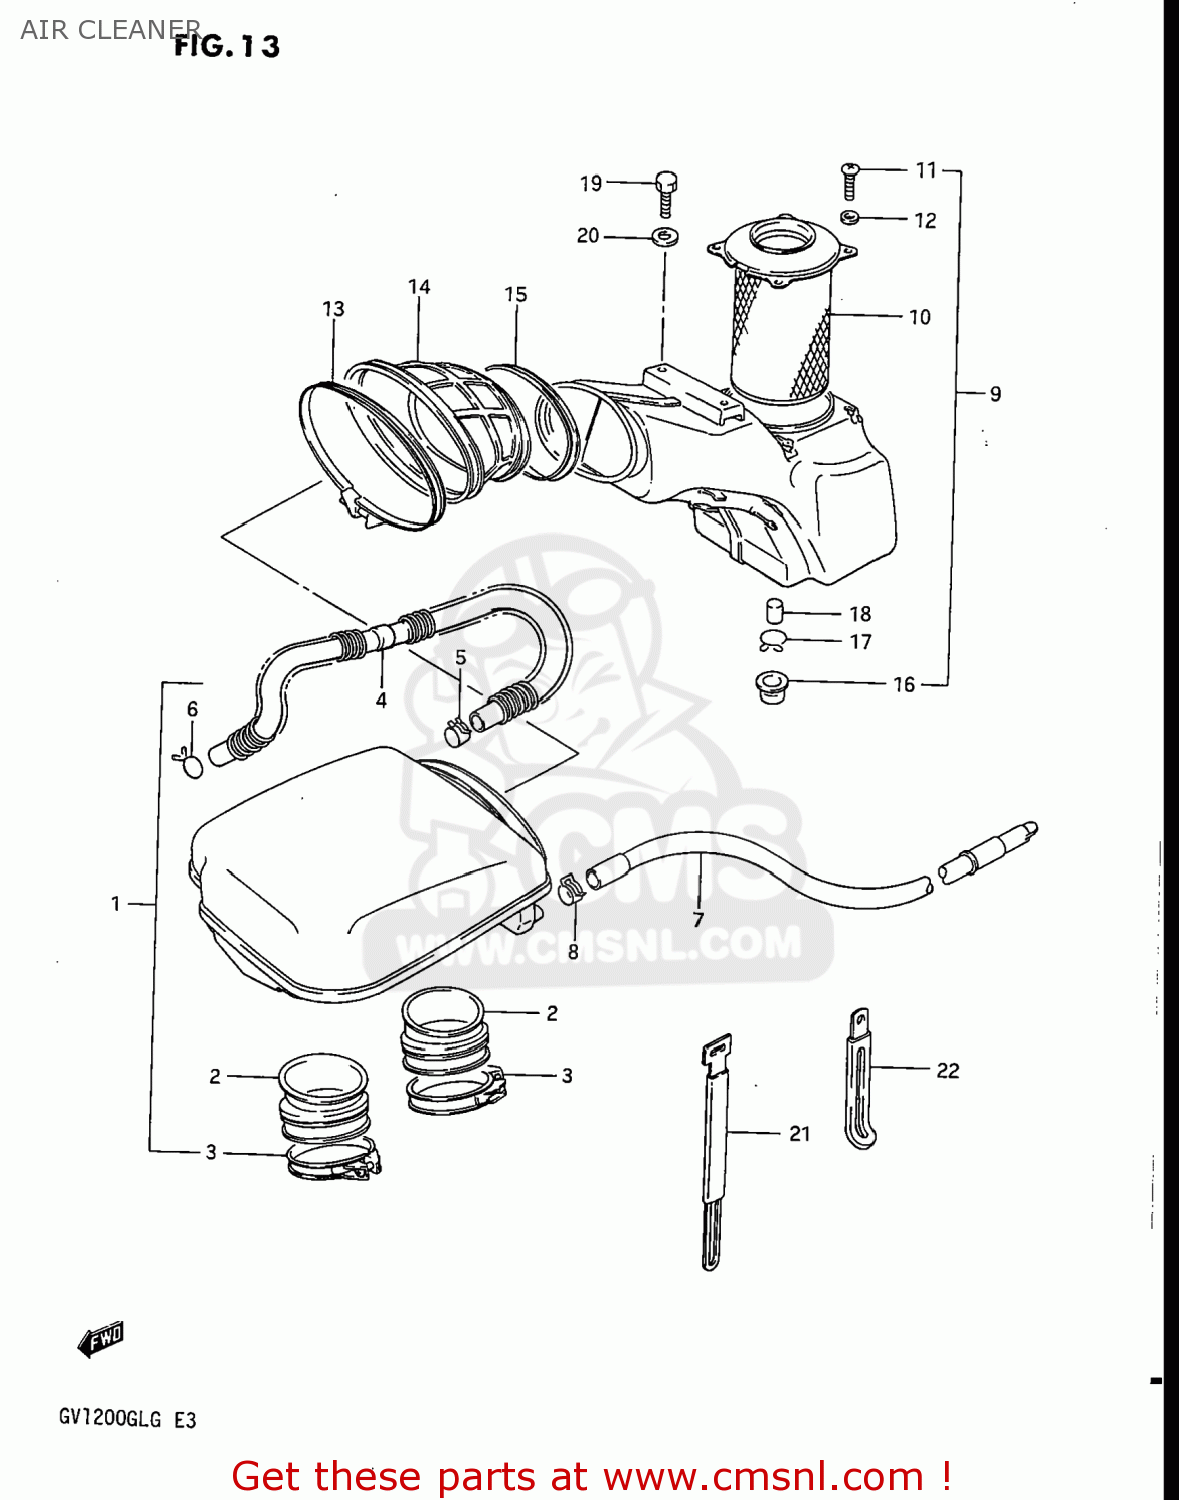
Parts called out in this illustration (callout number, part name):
1	CLEANER ASSEMBLY,AIR
2	TUBE,AIR CLEANER OUTLET
3	CLAMP
4	TUBE COMP,BREATHER
5	CLIP
6	CLIP,BREATHER TUBE
7	DRAIN TUBE
8	CLIP
9	CASE ASSEMBLY,AIR CLEANER
10	FILTER,AIR CLEANER
11	SCREW
12	WASHER,LOCK
13	CLAMP
14	GUARD,MUD
15	CLAMP
16	TUBE
17	CLIP
18	FILTER,DRAIN
19	BOLT, UPPER
20	WASHER
21	CLAMP L:110
22	CLAMP
